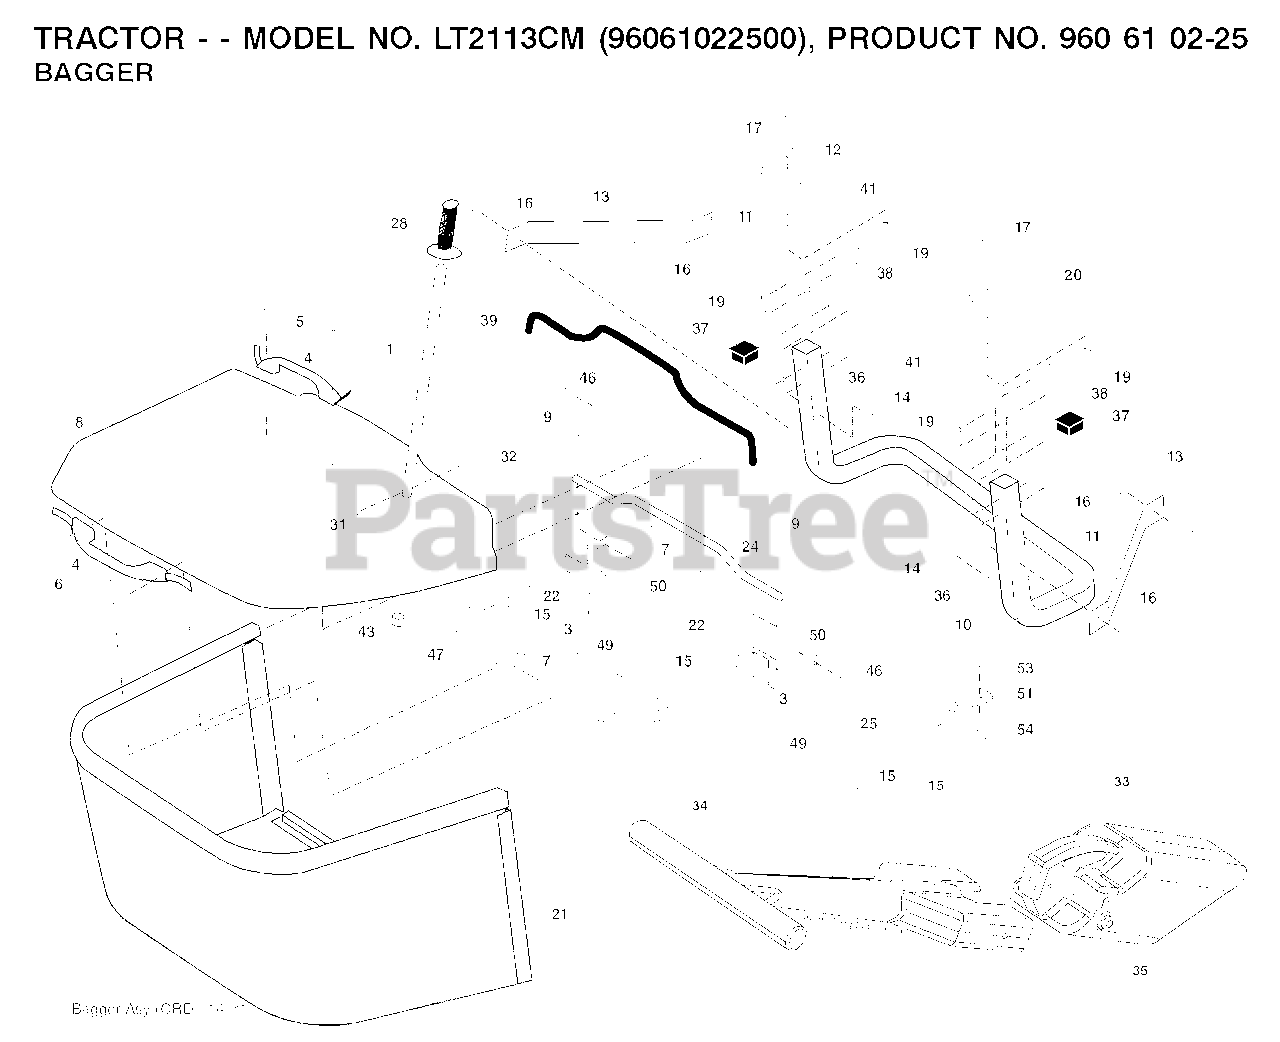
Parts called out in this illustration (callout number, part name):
1	TUBE HANDLE
3	NUT T
5	SCREW.PAN.HEAD
11	BRACKET
14	BOLT-HEX EAK
15	RETAINER-SPRNG RB
16	NUT LOCK FLG 3/8-16 UNC
17	BOLT
19	NUT LOCK HEX FLANGE 5/16-18
20	BRKT.PIVOT.RH.CRD
21	BAGGER.ASM.CRD.2007
22	BRACKET
24	TUBE
28	GRIP.HANDLE.BLACK
31	RETAINER CLIP
32	RIVET,DRILLED
33	PLUG
35	PIN
38	BOLT.5/16-18X2.5
39	SEAL.BAGGER.CRD
41	BRKT, BAGGER
43	PLUG, TUBING END
46	BOLT.CARRIAGE.5/16-18
50	NUT.71038.31-18.HEX.NYLOCK
53	NUT
54	BOLT
